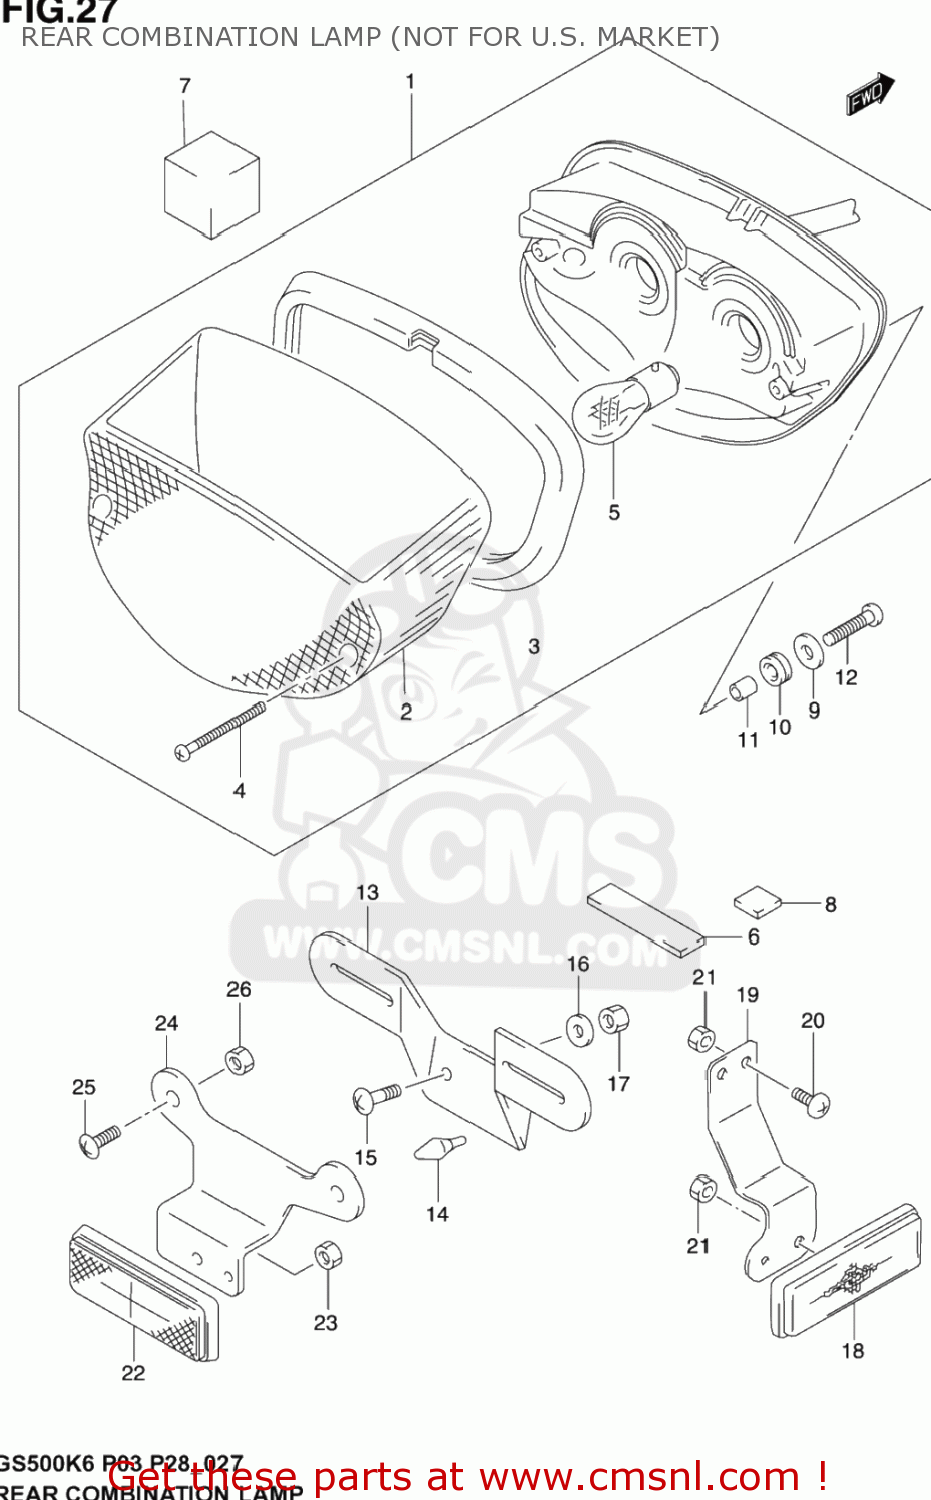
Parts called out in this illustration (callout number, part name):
1	LAMP ASSY,RR COMBINATION
2	LENS
3	GASKET,LENS (NAS)
4	SCREW
5	BULB(12V32/3CP)
6	CUSHION (80X20X10)
7	CUSHION, UPPER (40X40X38)
8	CUSHION, LOWER (20X20X6)
9	WASHER
10	CUSHION
11	SPACER(6.5X9X8.5)
12	SCREW
13	BRACKET,LICENSE PLATE
14	CUSHION
15	SCREW
16	WASHER
17	NUT
18	REFLECTOR ASSY,RR
19	BRACKET,RR SIDE REFLECTOR
20	SCREW 5X12
21	NUT
22	REFLECTOR REAR
23	NUT
24	BRACKET,RR RR
25	SCHRIOEF
26	NUT
